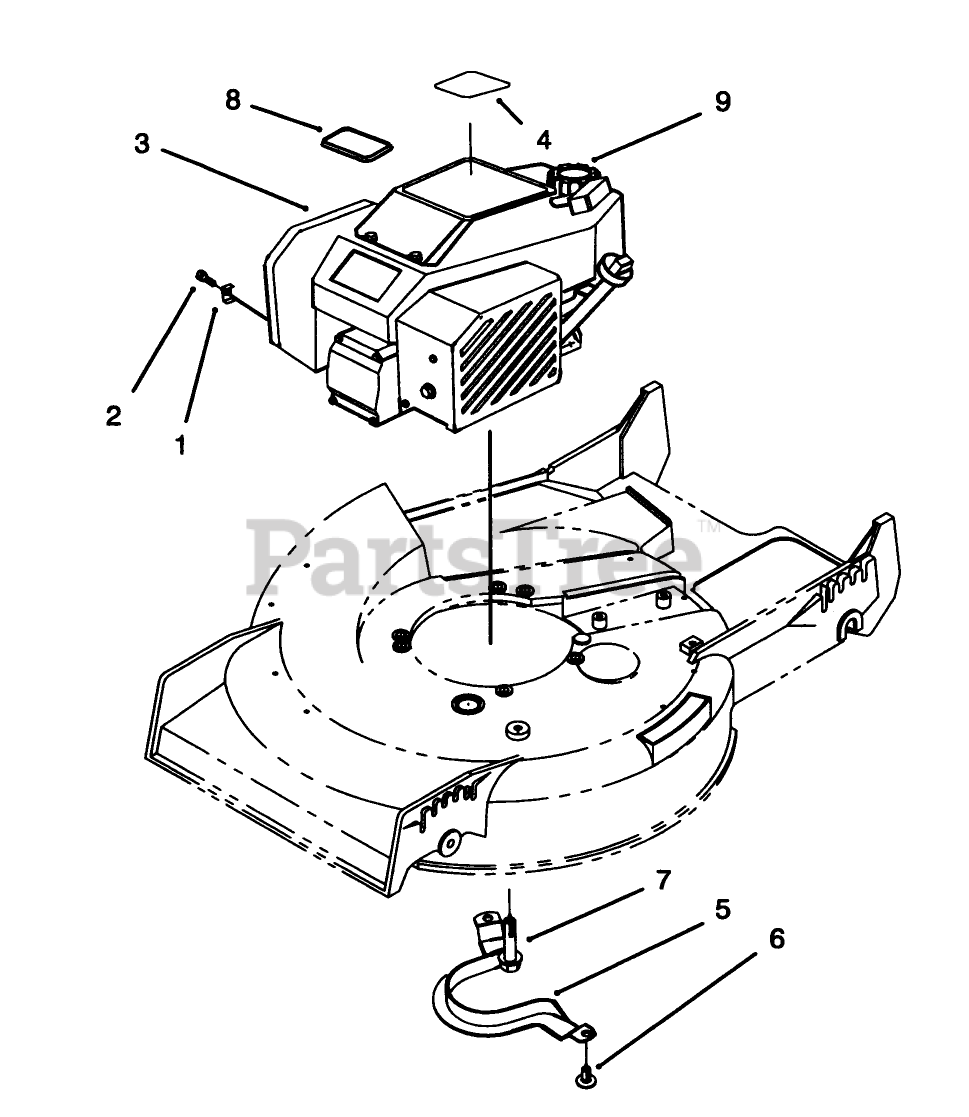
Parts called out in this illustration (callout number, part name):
1	CLAMP-CASING
2	Screw
3	Engine
4	DECAL - ENGINE
5	Guide-Belt
6	SCREW-HWHTF
7	SCREW-HWH
8	PLATE-LOGO
9	GAS CAP ASM
